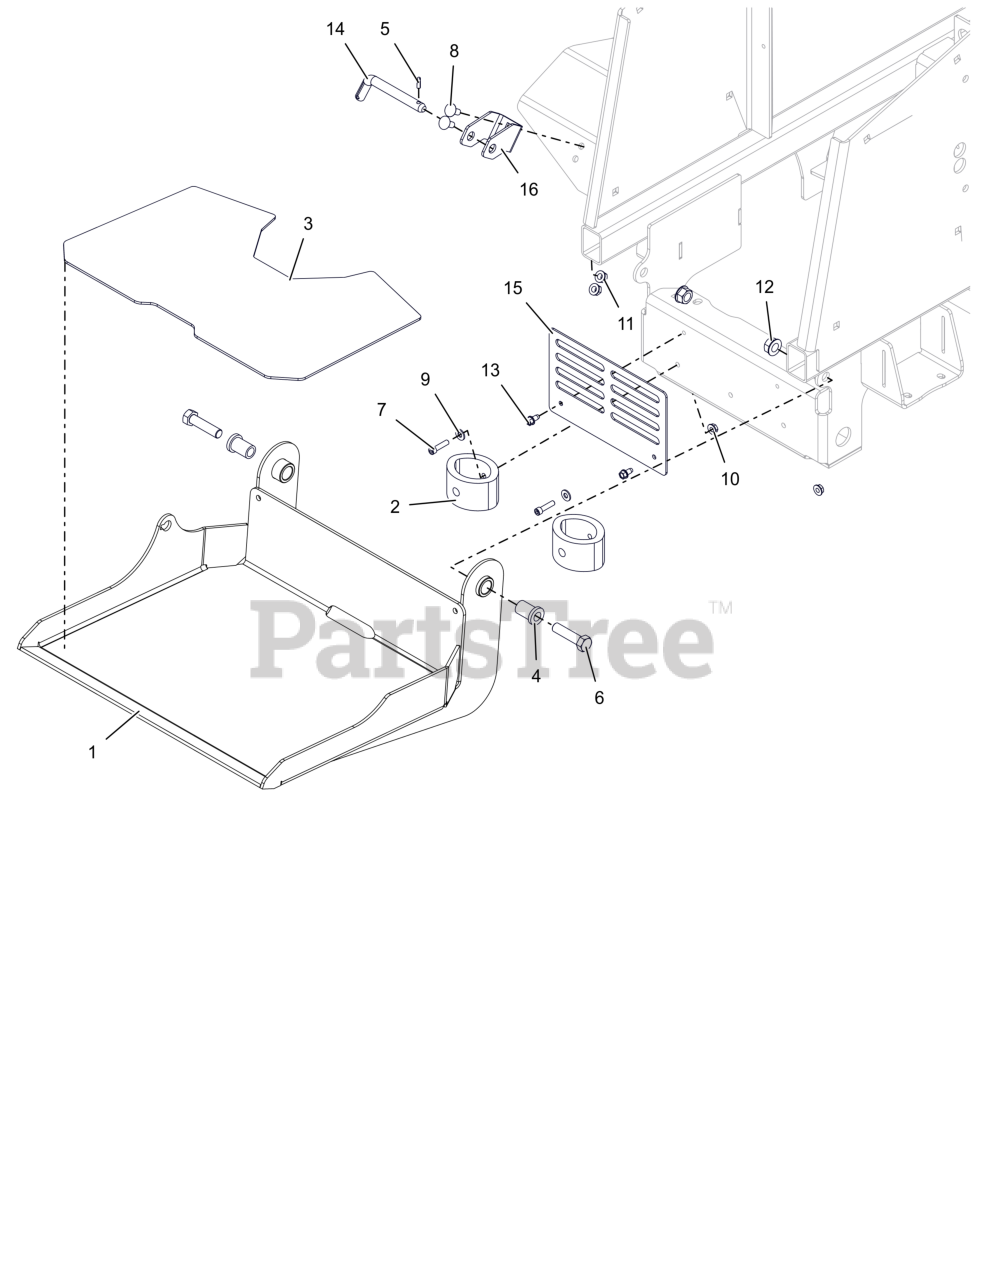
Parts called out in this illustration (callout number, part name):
1	WMT-32"Z-STANCE PLATFORM (RED)
2	BUMPER, PLATFORM
3	TAPE, OPERATOR PLATFORM GRIP
4	BSHG-FLG .515X.746X1.290X1.000
5	PIN-ROLL .188X.63
6	BLT, HEX .50-13X2.00 G5 ZCC
7	SCR, SKH .25-20X1.00
8	BLT, RHSSN.31-18X.750 G5 ZCC
9	WSHR,FLT .281X.625X.065 ZCC
10	NUT-LK-CTR-FLG .25-20 ZC120
11	NUT,LK-CTR-FLG .31-18 GF ZCC
12	NUT-LK-CTR-FLG .500-13 GG ZCC
13	SCR-TAP .25-20X.50 HWH ZCC
14	PIN- HOC SELECTOR
15	GUARD- 32" FOOT (RED)
16	BRKT- PLTFRM LOCK PIN MTG(RED)
